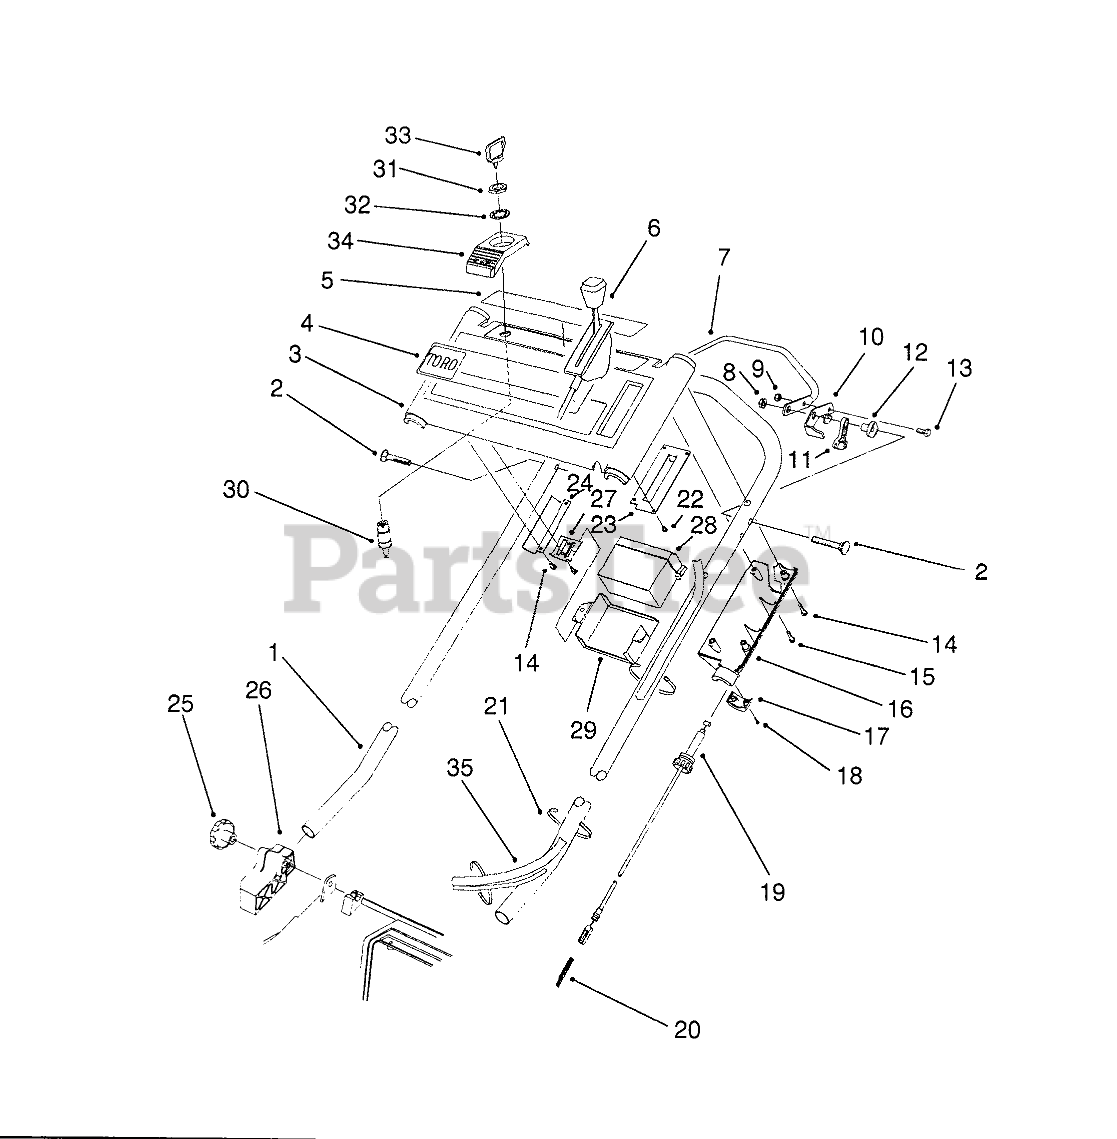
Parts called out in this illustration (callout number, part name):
1	Handle
2	SCREW-HANDLE
3	Panel-Control (Incl Ref. #4, & 5)
4	DECAL - TORO
5	DECAL - DANGER PANEL
6	Control-Throttle Bend Type #1 Sheath Lg. 42.50 Wire Lg. 2 1/2
7	CONTROL BAR
8	NUT-LOCK, NI
9	NUT-LOCK, NI
10	CONTROL LEVER
11	LEVER-TRACTION
12	SPACER-SUPPORT
13	SCREW-HH
14	SCREW-PPH, PLASTITE
15	Screw
16	Cover-Throttle Lower
17	LOWER THROTTLE CAP
18	#4-14X.62 PLASTITE SCW
19	TRACTION CABLE
20	SPRING-COMPRESSION
21	TIE-CABLE
22	#6-19X.25 PLASK FORM SC
23	THROTTLE PLATE
24	Bracket-Panel
26	MOUNT-HANDLE, RH
27	BATTERY BRACKET
28	Battery
29	BATTERY RETAINER
30	Switch-Starter (Incl. Ref. #31, & 32)
31	NUT-HH
32	WASHER-TOOTH, INTERNAL
33	KEY-IGNITION
34	IGNITION SWITCH BRACKET
35	WIRE HARNESS
